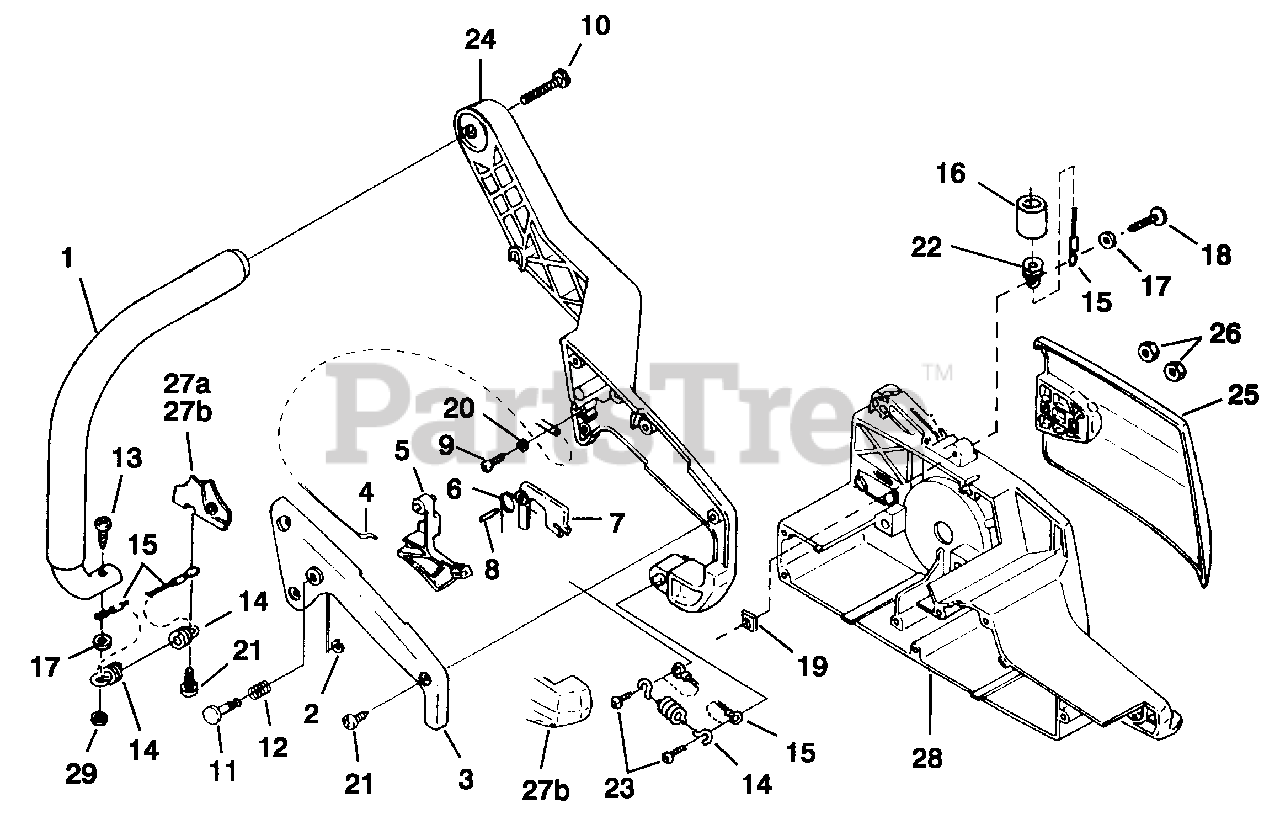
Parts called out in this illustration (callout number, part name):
1	HANDLE BAR
2	RING, RETAINING
3	COVER, REAR HANDLE
4	CABLE, THROTTLE
5	TRIGGER, THROTTLE
6	SPRING, THROTTLE
7	LOCK, THROTTLE
8	PIN, DOWEL
9	SCREW, THREAD FORM (6-19 X 1/2")
10	SCREW, HEX Hd (12-24 X 7/8")
11	PIN, THROTTLE LOCK
12	SPRING, COMPRESSION
13	SCREW, TORX (10-24 X 1/2")
14	SPRING, EXTENSION
15	RETAINER, SPRING
16	SLEEVE, SPRING
17	WASHER, FLAT (#12)
18	SCREW, PAN Hd. (10-24 X 7/8")
19	NUT, SQUARE (# 10-24)
20	WASHER, FLAT
21	SCREW, THREAD FORM (8-16 X 5/8")
22	SPRING, EXTENSION
23	SCREW, THREAD FORM (8-16 X 1/2")
24	HANDLE, REAR
25	COVER, DRIVE CASE
26	NUT, HEX
27A	HSG., STARTER SIDE
27B	HSG., STARTER SIDE
28	ENG. HSG. DRIVE SIDE
29	NUT, HEX
